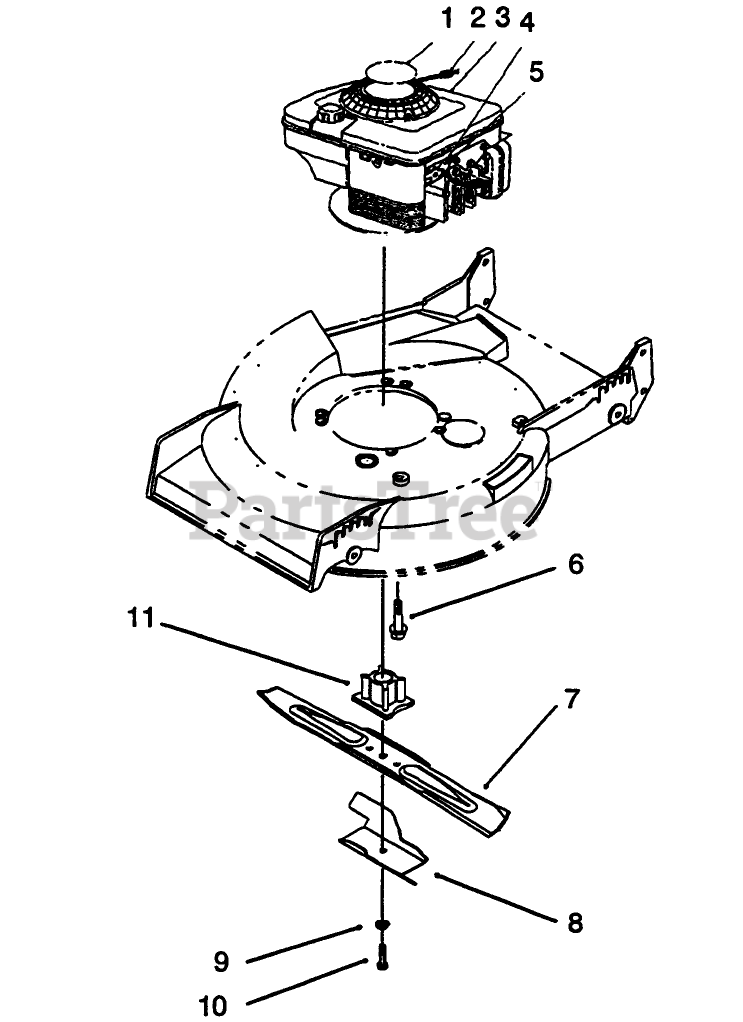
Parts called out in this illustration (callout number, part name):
1	DECAL-ENGINE F/W ENGINE
2	STOP-ROPE
4	CLAMP-CASING
5	Screw
6	SCREW-HWH
7	Blade
8	Accelerator
9	WASHER-LOCK
10	SCREW-BLADE
11	BLADE RETAINER
